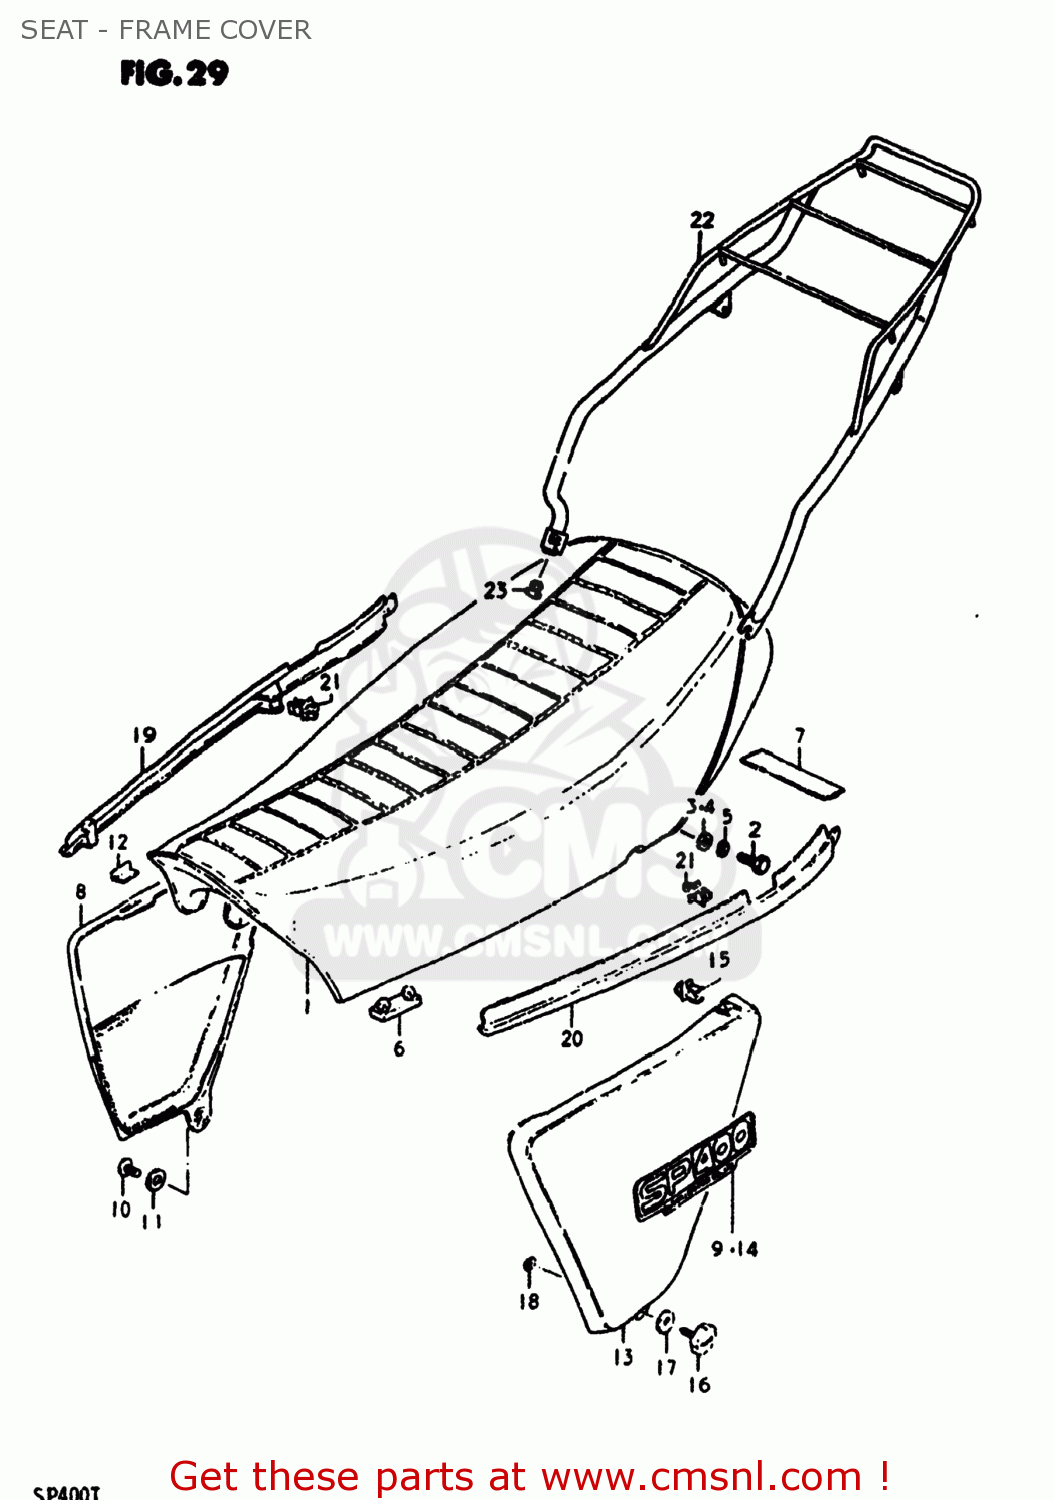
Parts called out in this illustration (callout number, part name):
1	SEAT ASSEMBLY
2	BOLT
3	WASHER
4	WASHER (8.2X20X1.6)
5	LOCK WASHER
6	CUSHION
7	CUSHION,FRAME
8	COVER,FRAME,R(BLACK)
9	EMBLEM
10	SCREW
11	WASHER
12	CUSHION,FRAME COVER
13	COVER,FRAME,LEFT
14	EMBLEM
15	CLAMP
16	KNOB,FRAME COVER,R
17	WASHER
18	NUT
19	COVER,FRAME
20	COVER,SEAT,LOWER,LEFT
21	CLAMP
22	CARRIER
23	CAP(OD:17)
